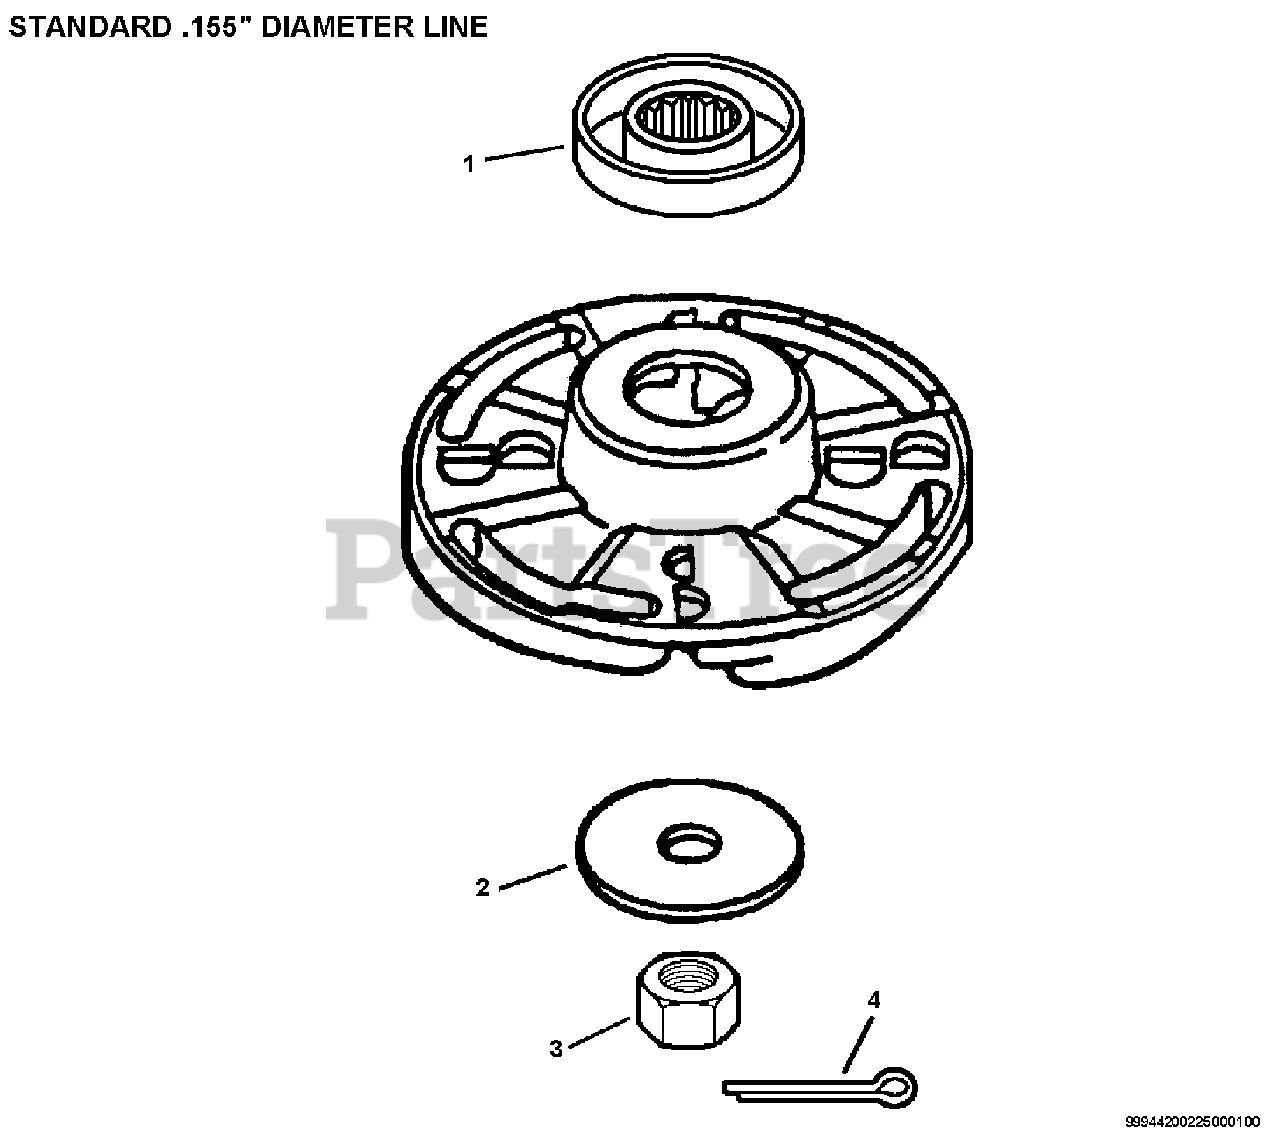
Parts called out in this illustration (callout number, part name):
1	ADAPTOR
2	ADAPTOR, BLADE - LOWER
3	NUT - 10 -- LEFT HAND
4	PIN, SPLIT - 2X22
